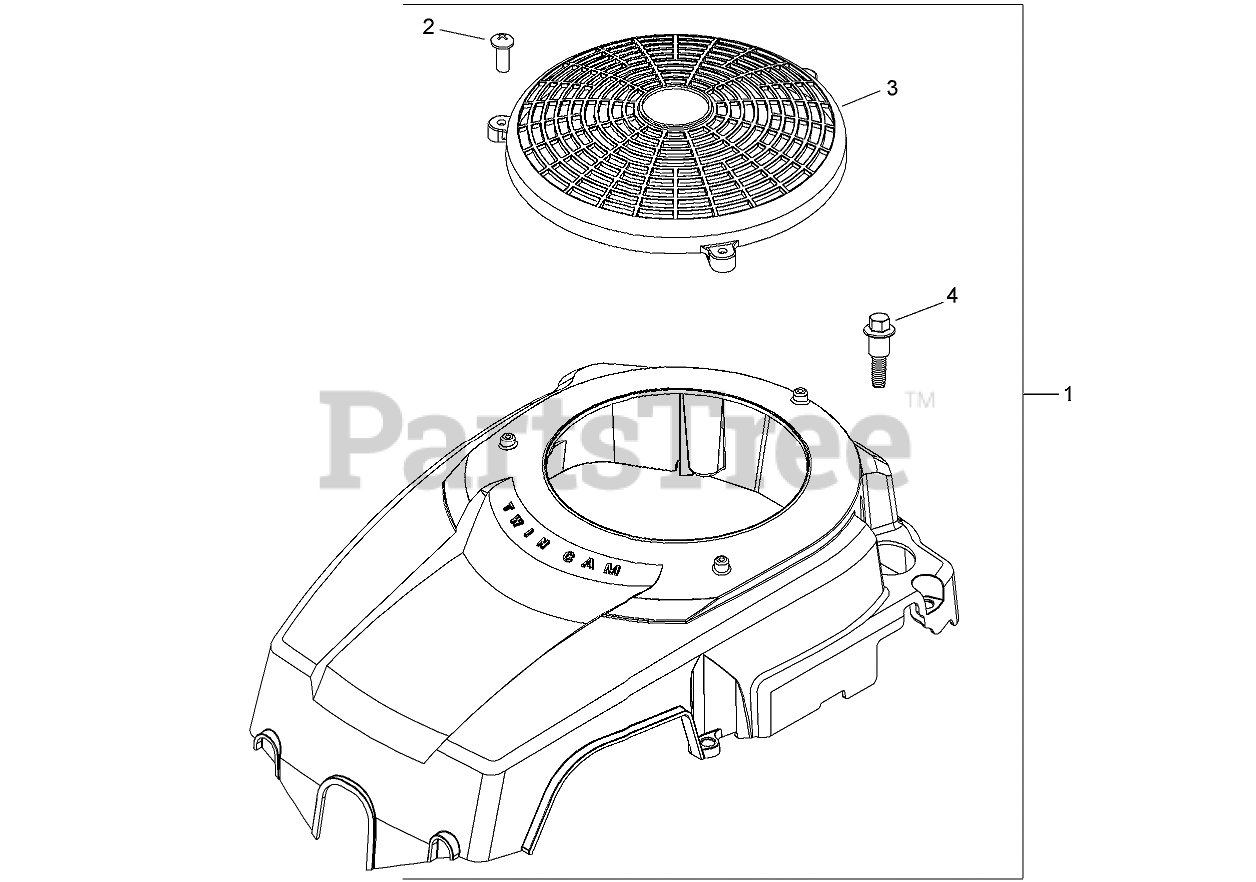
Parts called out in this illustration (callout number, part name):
1	BLOWER HOUSING AND GUARD KIT
2	SCREW-PPH (11-16X1/2)
3	GUARD-FIXED
4	Bolt-Shoulder (M6x1x26)
